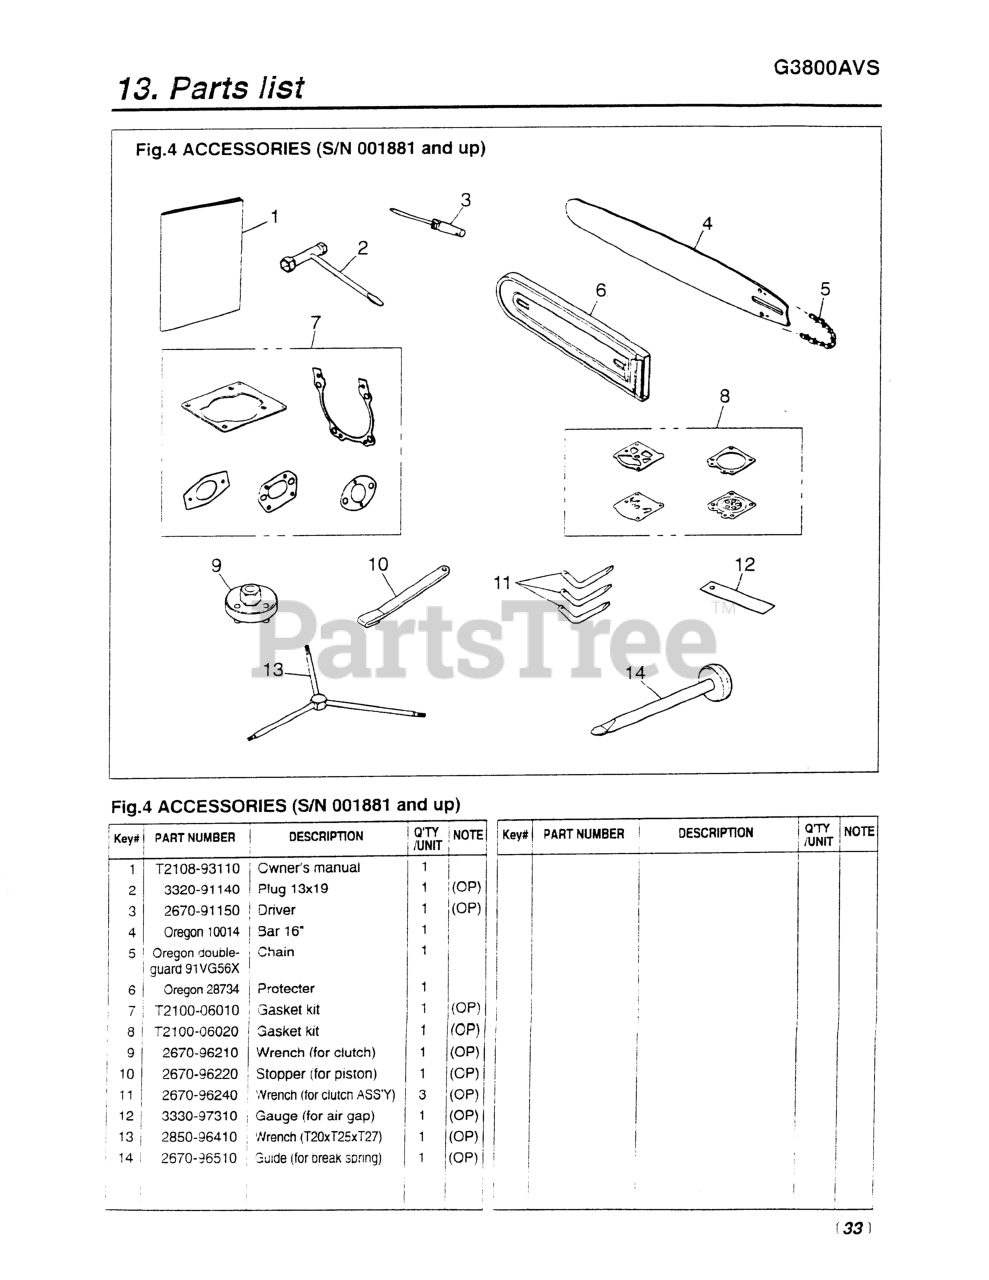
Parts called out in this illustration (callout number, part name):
2	WRENCH, PLUG
3	SCREWDRIVER
4	BAR 16
6	PROTECTOR (OREGON 28734)
7	KIT, GASKET (G3800AVS)
8	KIT, GASKET (G3800AVS)
9	WRENCH (TOOL)
10	STOPPER (TOOL)
11	WRENCH (TOOL)
12	GAUGE (TOOL)
13	WRENCH (RPLS. 2670-96410)
14	GUIDE (TOOL)
